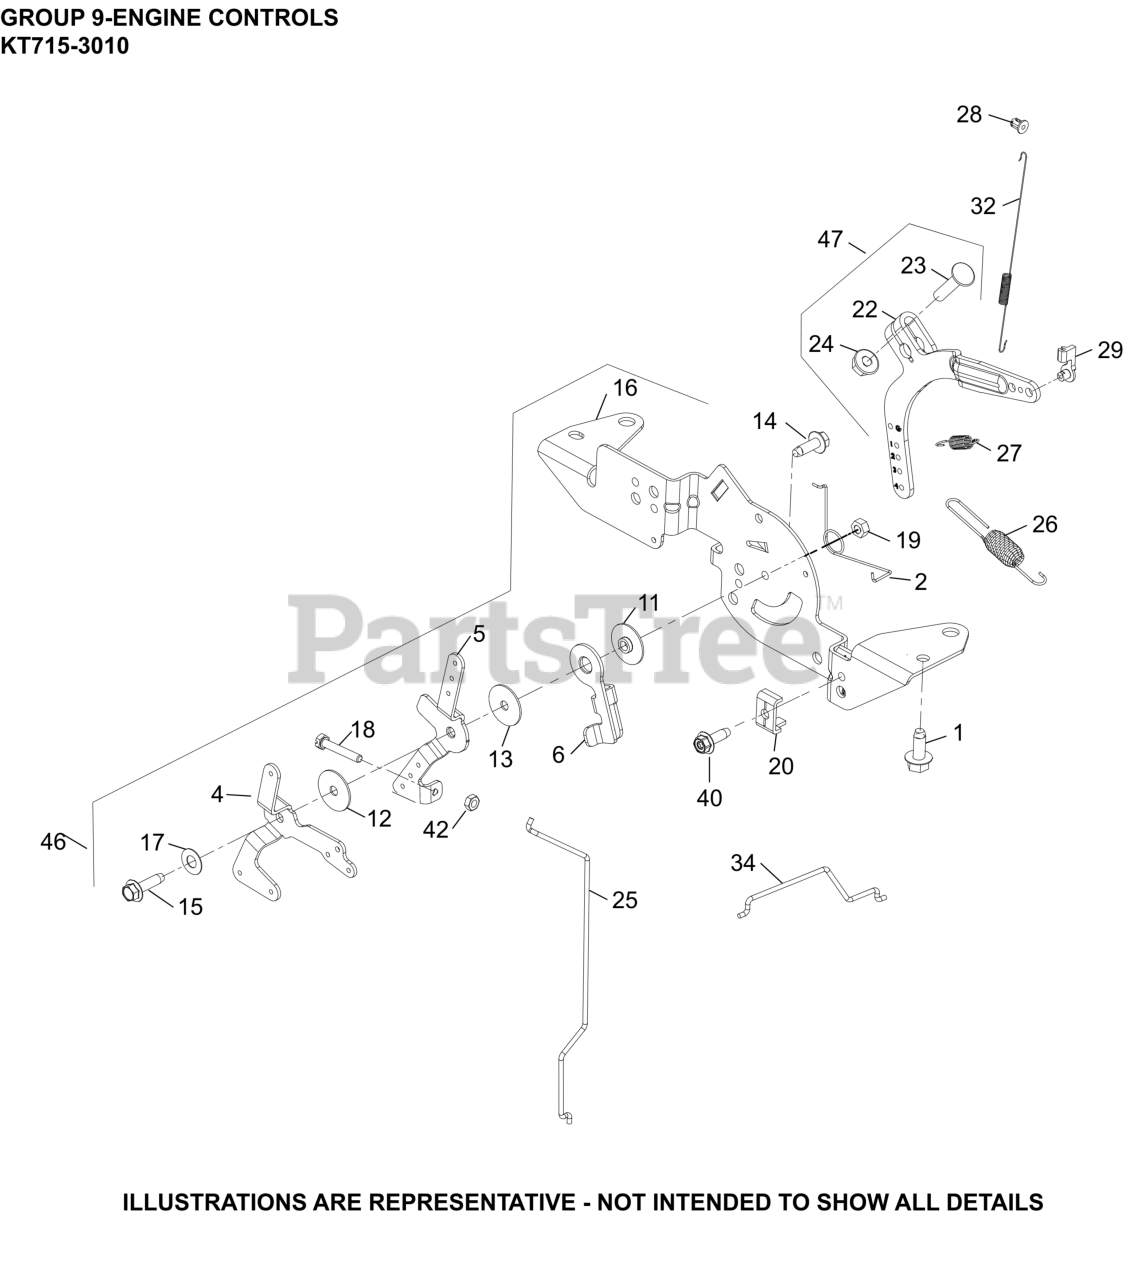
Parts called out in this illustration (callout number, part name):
1	SCREW, THREAD FORMING
2	SPRING, CHOKE RETURN
4	LEVER, CHOKE
5	LEVER, THROTTLE CONTROL
6	LEVER, THROTTLE ACTUATOR
11	SPACER, CONTROL ASSEMBLY
12	WASHER, FLAT 5.5 MM
13	WASHER, FLAT 5 MM
14	SCREW, THREAD FORMING
15	SCREW, THD FRM-USE 25 086 473-S
16	BRACKET, SPEED CONTROL
17	WASHER, SPRING 1/4"
18	SCREW, SLT HD CAP M4X0.7X25
19	NUT, LOCK M5X.8
20	CLAMP, CABLE CABLE
22	LEVER, GOVERNOR - (#2409069S)
23	BOLT, RD HD SQ NECK M6X1.0X25
24	NUT, FLG M6X1.0
25	LINKAGE, CHOKE
26	SPRING, GOVERNOR (ORANGE)
27	SPRING, GOVERNED IDLE
28	BUSHING, LINKAGE RETAINING
29	BUSHING, THROTTLE LINKAGE
32	SPRING, LINKAGE
34	LINKAGE, THROTTLE
40	SCREW, THREAD FORMING
42	NUT, M4X0.7
46	CONTROL ASSEMBLY, DUAL WIRE
47	LEVER, GOVERNOR ASSEMBLY
